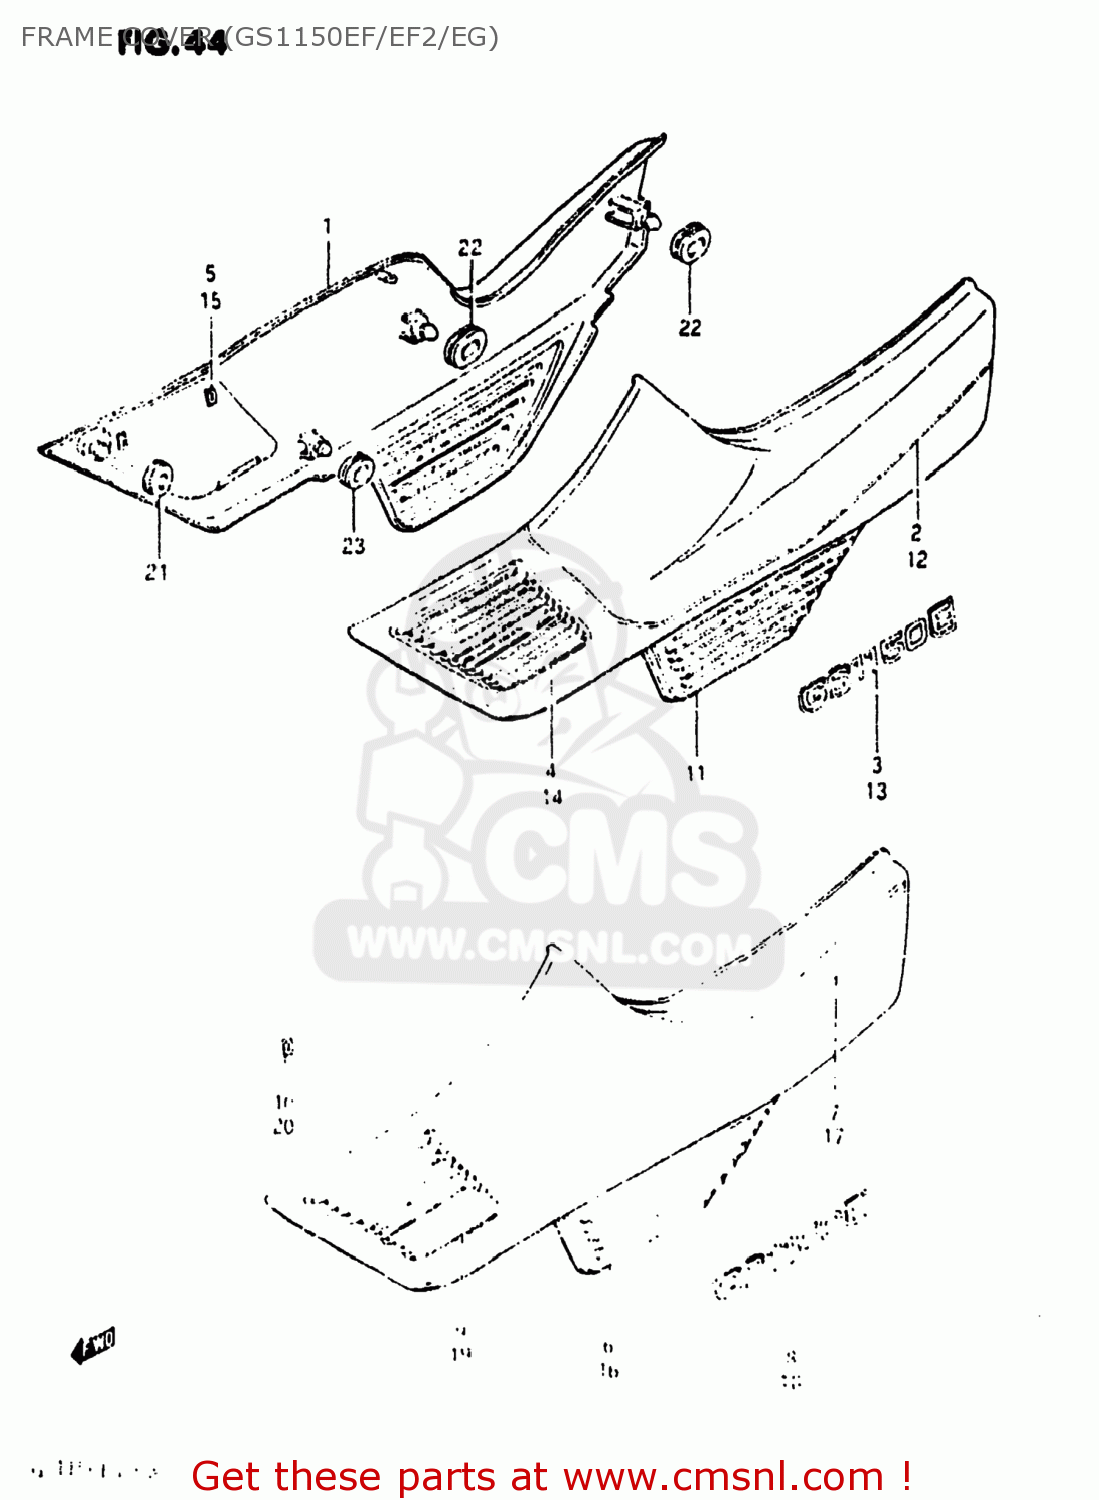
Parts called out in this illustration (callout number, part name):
1	COVER,FRAME,RIGHT
2	TAPE SET,FRAME COVER,RIGHT
3	EMBLEM
4	COVER,FRAME,RIGHT
5	NUT
6	COVER ASSEMBLY,FRAME BODY
7	TAPE SET,FRAME COVER
8	EMBLEM
9	COVER,FRAME,RIGHT NO.1
10	NUT
11	COVER ASSEMBLY,FRAME,LEFT
12	TAPE,FRAME COVER
13	EMBLEM
14	COVER,FRAME,RIGHT NO.1
15	NUT
16	COVER,FRAME,LEFT
17	TAPE,FRAME COVER
18	EMBLEM
19	COVER,FRAME,RIGHT NO.1
20	NUT
21	CUSHION
22	CUSHION
23	CUSHION
